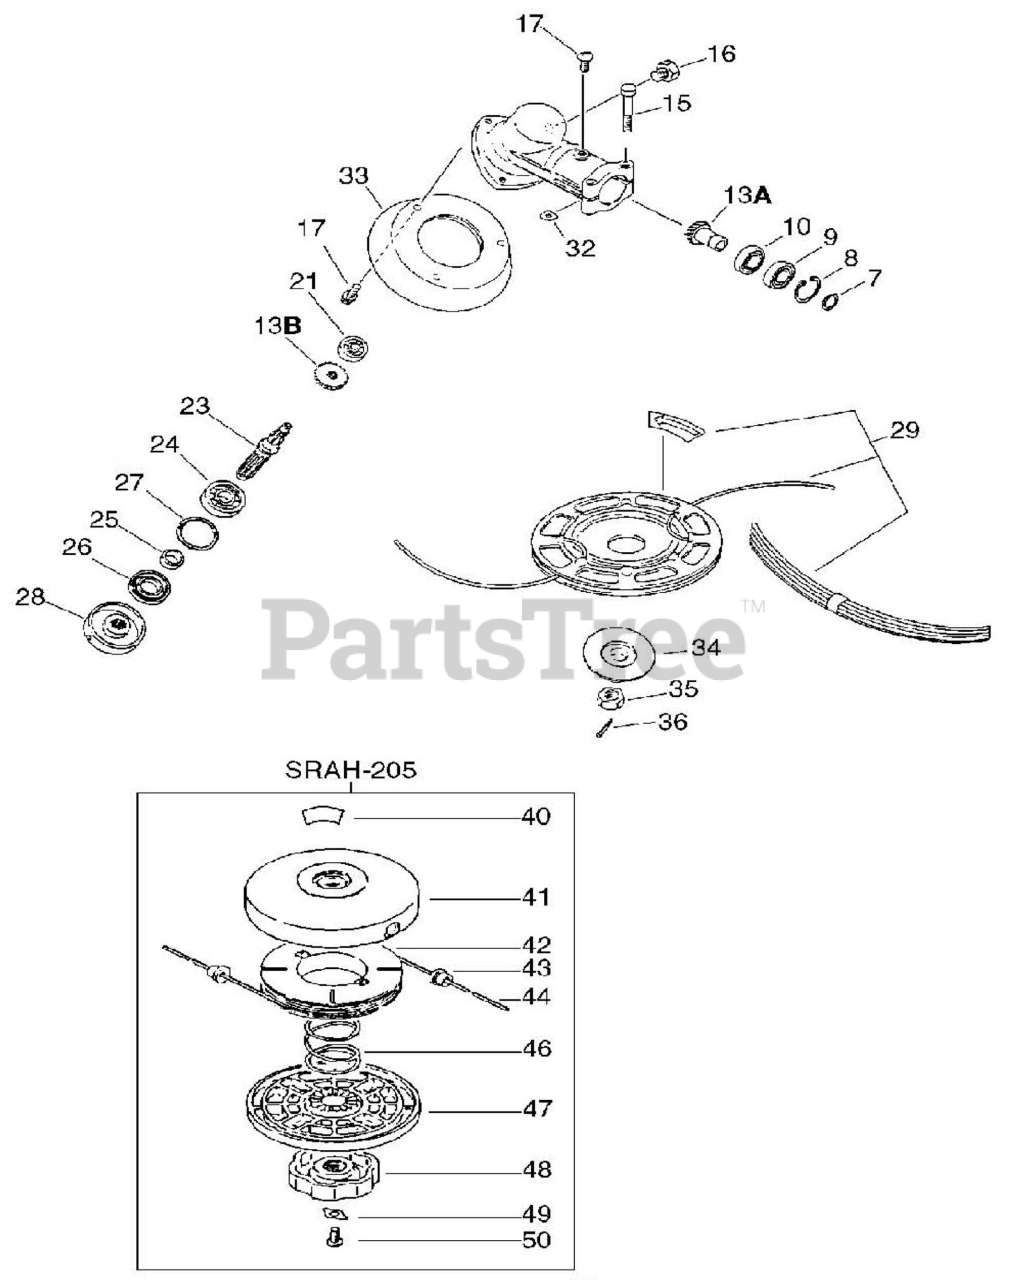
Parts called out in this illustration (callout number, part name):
7	RING, SNAP Ø10
8	RING, SNAP Ø22
9	BEARING, BALL 6900Z
10	BEARING, BALL 6900
13	GEAR SET
15	BOLT 5×28
16	BOLT M8×8
17	SCREW 5×10
21	BEARING, BALL 626
23	SHAFT, GEAR
24	BEARING, BALL 6000
26	SEAL, OIL
27	RING, SNAP 26
28	PLATE, ADAPTOR - UPPER
29	TRIMMER HEAD
32	D-WASHER
33	PLATE, SHIELD
34	PLATE, ADAPTOR
36	PIN, COTTER 2×22
40	LABEL - CAUTION
41	HOUSING ASSY, SPOOL
42	REEL, ROPE
44	LINE, TRIMMER
46	SPRING
47	COVER, SPOOL
48	KNOB, SCREW
49	NUT
50	SCREW 6×10
